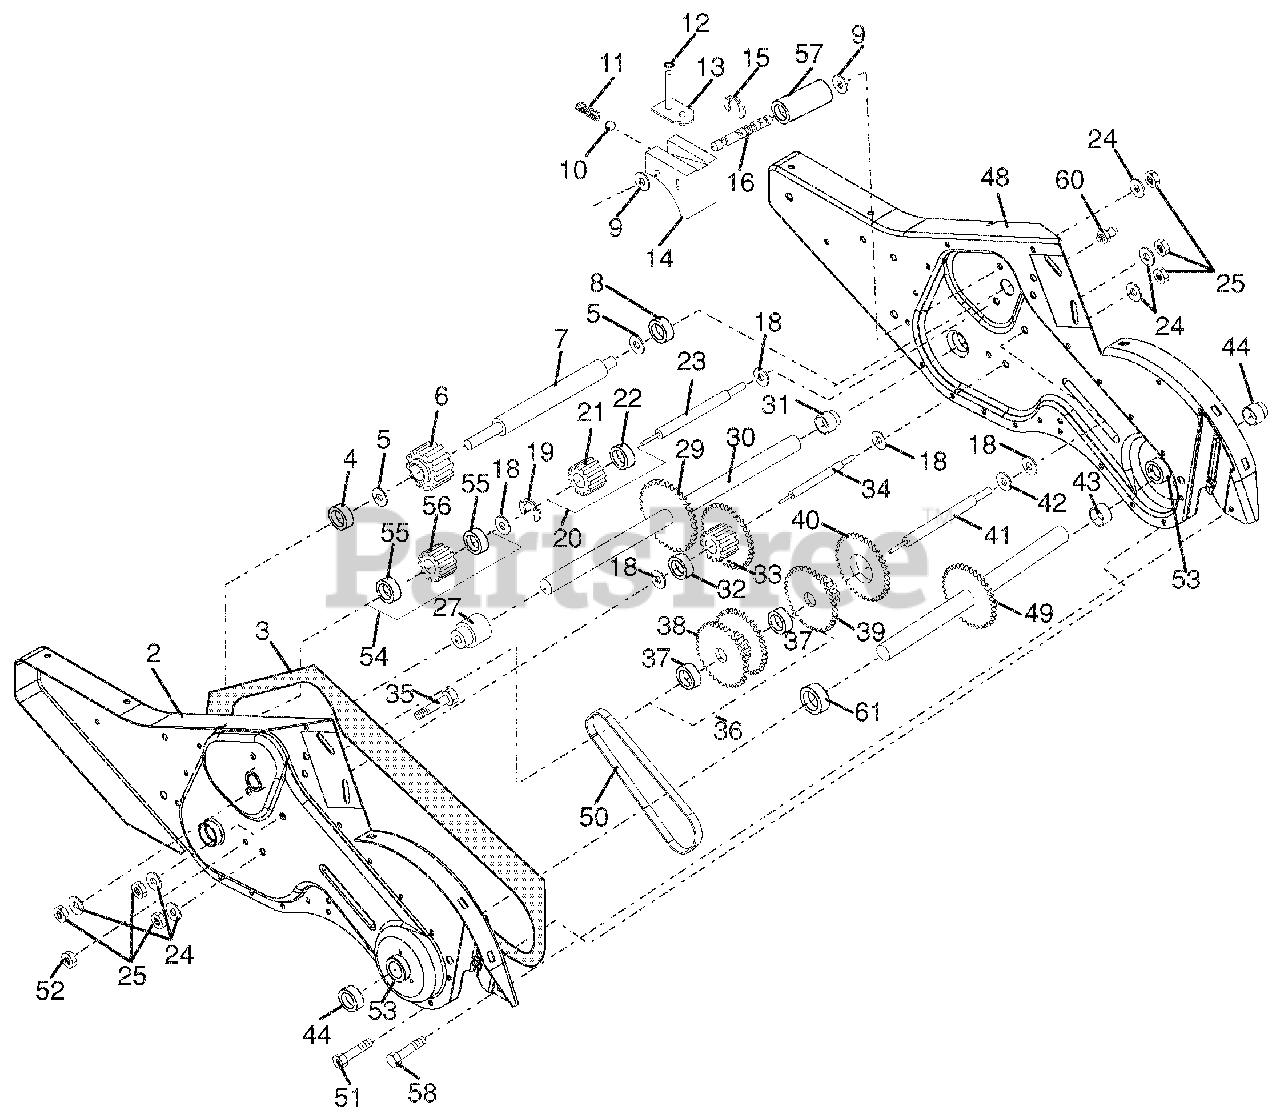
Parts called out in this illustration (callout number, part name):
1	TRANSMISSION ASSEMBLY COMPLETE
2	Gearcase, LH w/Bearing (Includ
3	GASKET, GEARGASE
4	Bearing, Needle
5	Washer, Thrust 5/8 x 1.10 x 1/
6	ARM.BRAKE
7	Shaft, Input
8	Bearing, Needle
9	Washer, Seal
10	Ball, Steel
11	Spring, Shift, Fork
13	Arm, Shift
14	Fork, Shift
15	Ring, Klip
16	Shaft, Shift
19	Ring, Klip
20	Gear, Assembly, Reverse Idler
21	Gear, Reverse Idler
22	Bearing, Needle
23	Shaft, Reverse Idler
24	WASHER.LOCK.HVY HLCL.SPR.7/16
25	Nut, Hex 7/16-20
27	BEARING, SHAFT, GROUND DRV LH
29	Chain #35-50 Pitch
30	Ground Shaft Assembly
31	Bearing, Shaft, Ground Drive R
32	Spacer 0.70 x 1.00 x 1.150
33	Sprocket and Gear Assembly
34	Shaft, Reduction (2nd)
35	Screw, Whiz, Lock 5/16-18 x 3-
36	Sprocket Assembly w/Bearing (I
37	Bearing, Needle
38	Sprocket, Tine
39	Gear, Cluster, Red 1st & 2nd
40	Gear, Reverse
41	Shaft, Reduction (1st)
42	Washer, Thrust
43	Spacer 1.01 x 1.75 x 0.760
44	Seal Asm. Oil
48	Gearcase, RH w/Bearing (Includ
49	SHAFT, TINE
50	Chain, Roller #50-50 Pitch
52	Nut, Hex 5/16-18
53	Bearing Kit, Tine Shaft
54	Gear, DRT Idler w/Bearing (Inc
55	Bearing, Needle
56	Gear, DRT Idler
57	Spacer, Split .52 x .64 x 1.04
58	Screw 1/4-20 x .875
60	Fitting Grease
61	SPACER 1.015 X 1.50 X .650
